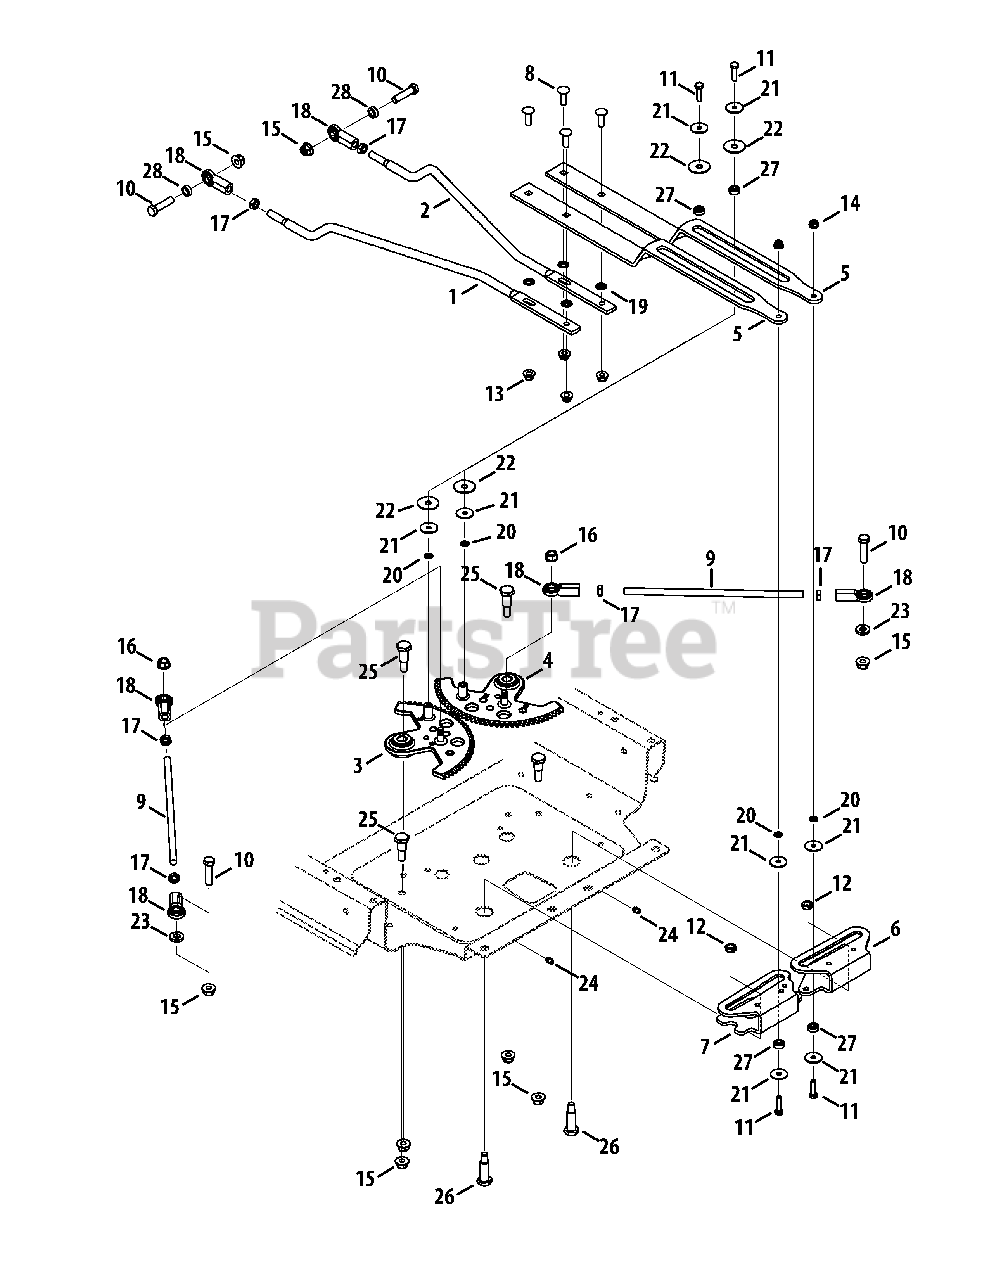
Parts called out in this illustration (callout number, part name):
1	Hydro Link, RH
2	Hydro Link, LH
3	Steering Gear Assembly, RH
4	Steering Gear Assembly, LH
5	Control Link
6	Speed Cam Plate, LH
7	Speed Cam Plate, RH
8	Carriage Screw, 5/16-18 x 1.00
9	Drag Link, .375 Dia.
10	Hex Screw, 3/8-16 x 1.50
11	Hex Screw, 1/4-20 x 1.00
12	Nut, Jamlock, 3/8-16
13	Flange Lock Nut, 5/16-18
14	Flange Lock Nut, 1/4-20
15	Flange Lock Nut, 3/8-16
16	Nut, 5/16-18, Centerlock
17	Jam Nut, 3/8-24
18	Female Ball-Joint
19	Speed Nut, .3125 ID
20	Push Nut, .25 ID x .50 OD
21	Flat Washer, .285 x 1.25 x .060
22	Washer, .355 x 1.25 x .048
23	Flat Washer, .407 x .812 x .135
24	Grease Fitting, 3/16
25	Shoulder Screw, 3/8-16 x .625 x .875
26	Shoulder Screw, .500 x 1.25 x 3/8-16
27	Ball Bearing, .25 x .625
28	Spacer, .380 ID x .625 OD x .21
